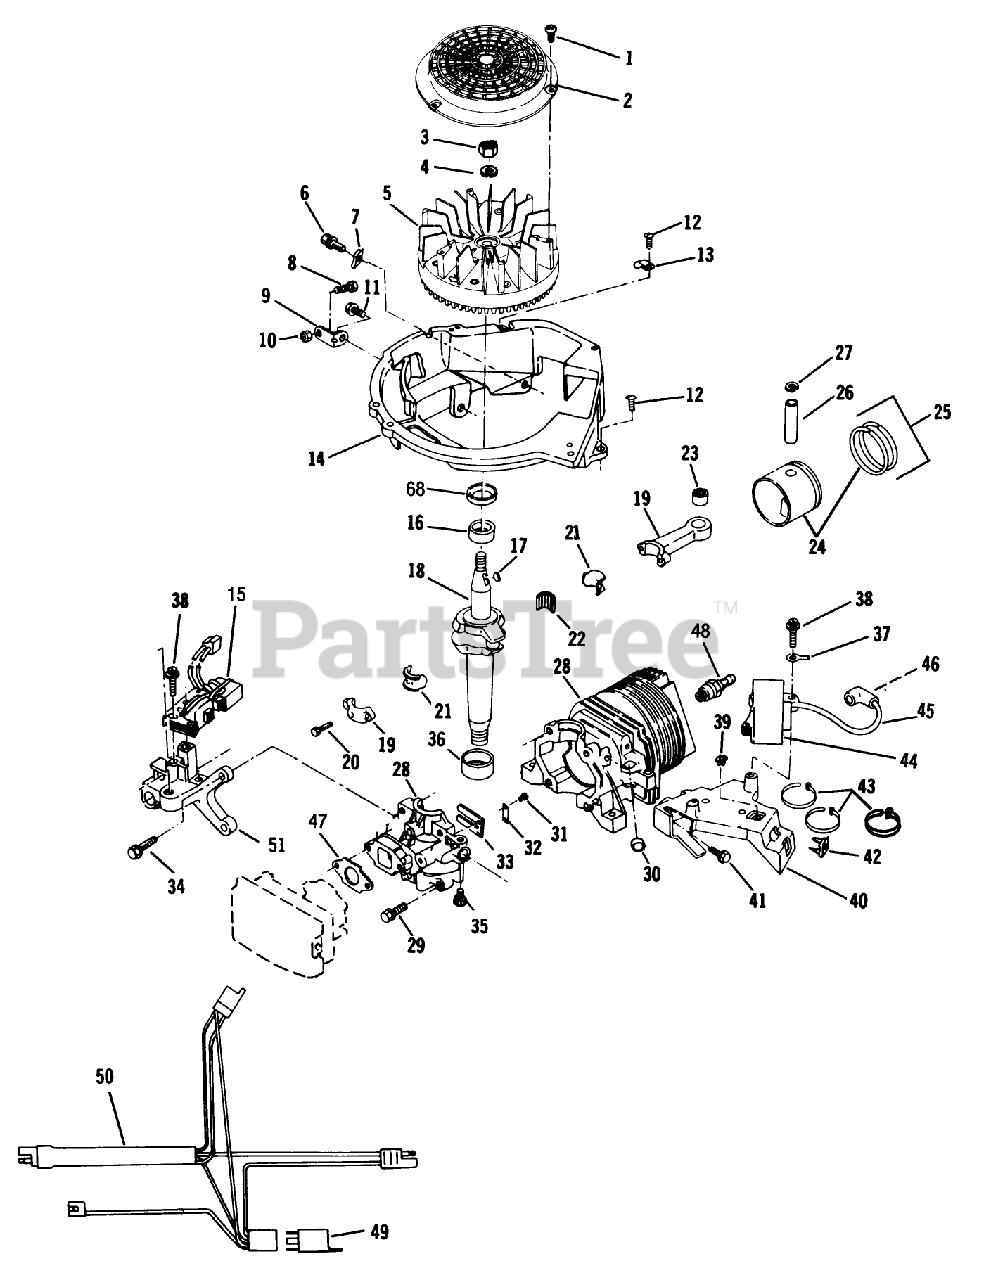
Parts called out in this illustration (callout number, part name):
1	SCREW F
3	NUT
5	FLYWHEEL ASSY F
6	SCREW-SEMS
8	BOLT F
10	NUT-LOCK F
12	SCREW F
16	BEARING V
17	KEY
20	SCREW-HSH
21	LINER ASM
23	BEARING AY F
27	RING-RETAINING
29	SCREW S
30	PLUG-CORE VF
31	SCREW-HH
32	PLATE-BACKUP, REED
36	BEARING V
37	TERMINAL S
39	NUT-CLIP
42	NUT-CLIP
45	HT LEAD&COVER XEV
47	GASKET CARB S
52	SEAL-OIL
